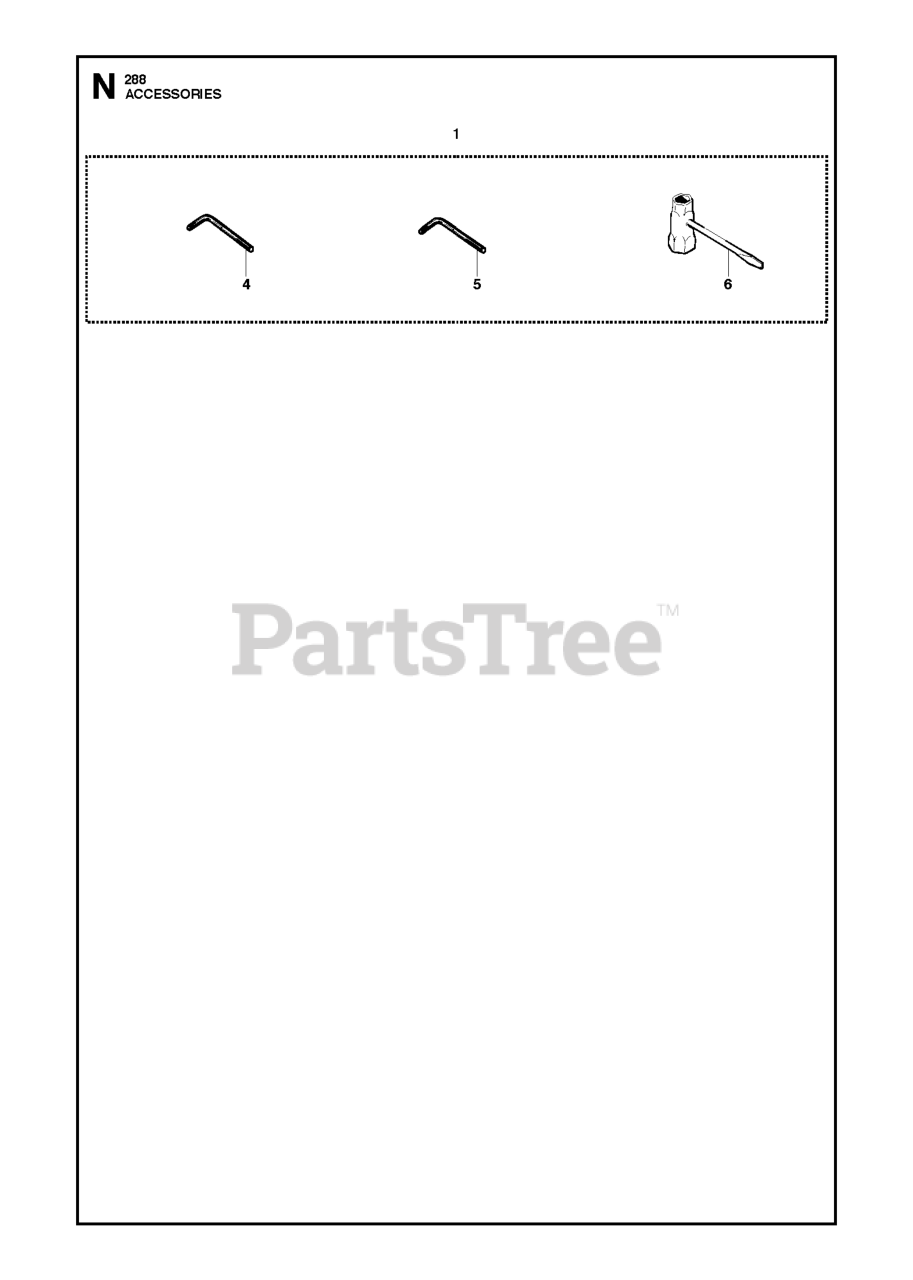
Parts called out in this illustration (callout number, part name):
1	TOOL KIT
4	L-SPANNER
5	L-SPANNER
6	COMBI TOOL
7	Grease Gun
8	GREASE
